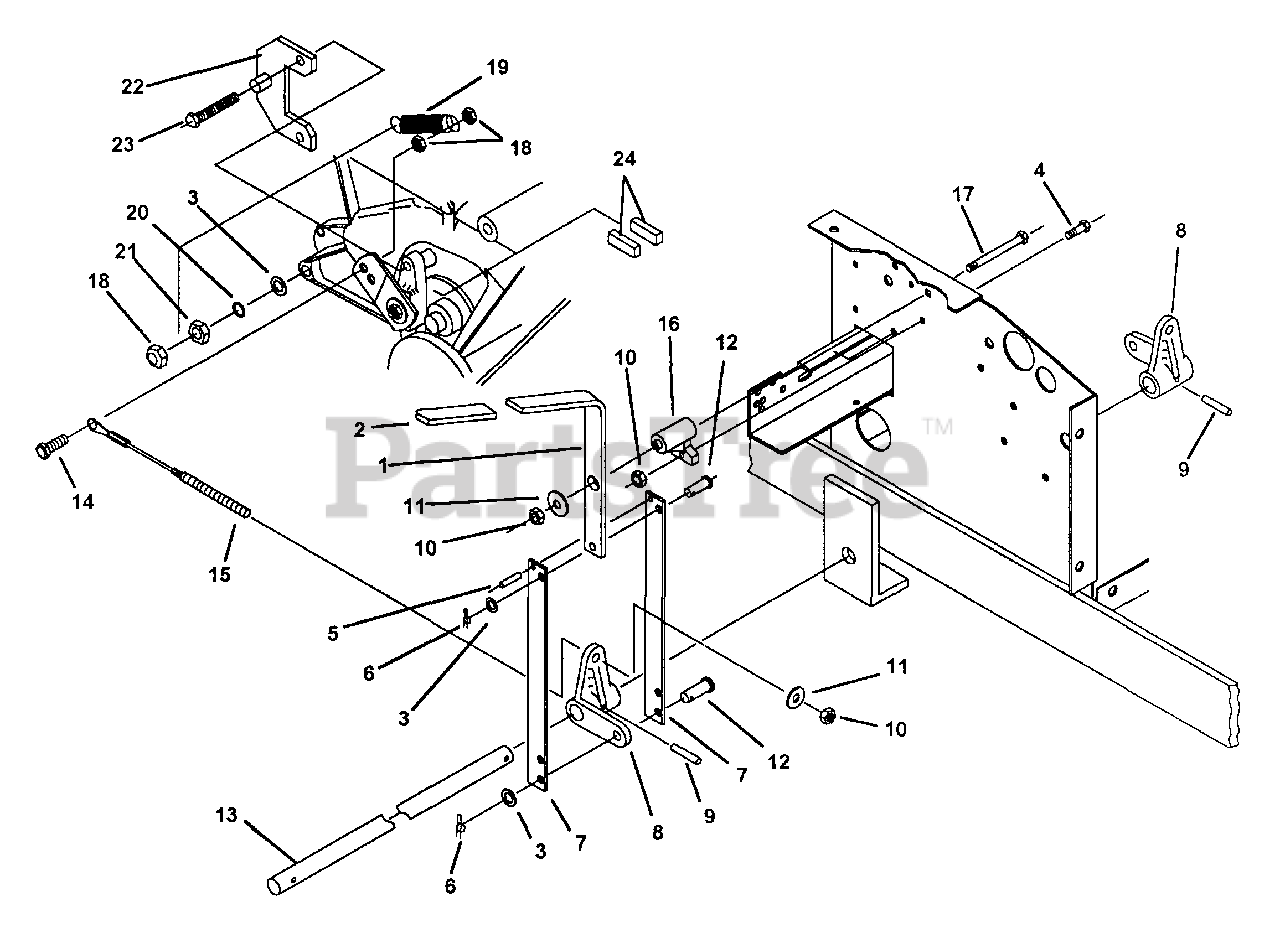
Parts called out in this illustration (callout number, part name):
1	BRAKE HANDLE
2	GRIP, HANDLE
3	WASHER, FLAT STD. 5/16"
4	BOLT, 1/4-20 X 1" GR. 5
5	ROLL PIN, 3/16 X 7/8" LONG, SPIRAL
6	COTTER, RUE RING 5/16-3/8 PIN
7	HANDLE LINK
8	BRAKE ARM
9	ROLL PIN, 3/16 X 1" LONG SPIRAL
10	NUT, 1/4-20 NYLOCK (Quantity Of 4 Can Be Used As Well)
11	WASHER, FLAT STD. 1/4" (Quantity Of 3 Can Be Used As Well)
12	CLEVIS PIN, 5/16 X 7/8" LONG
13	BRAKE ROD
14	BOLT, 5/16-18 X 3/4" GR. 5
15	CABLE ASSEMBLY, BRAKE
16	BRAKE LEVER MOUNT
17	BOLT, 1/4-20 X 3", HEX HEAD
18	NUT,5/16" X 18 STOVER
19	SPRING, EXT., 7/16" X 2-1/2"
20	LOCKWASHER, 5/16" SPLIT SPRING
21	NUT, 5/16-18 PLAIN
22	BRAKE STOP PLATE ASSEMBLY
23	BOLT, 1/4-20 X 1-1/2" GR. 5 W/PATCH (COMES W/GEARBOX)
24	BRAKE PUCK, REPLACEMENT
